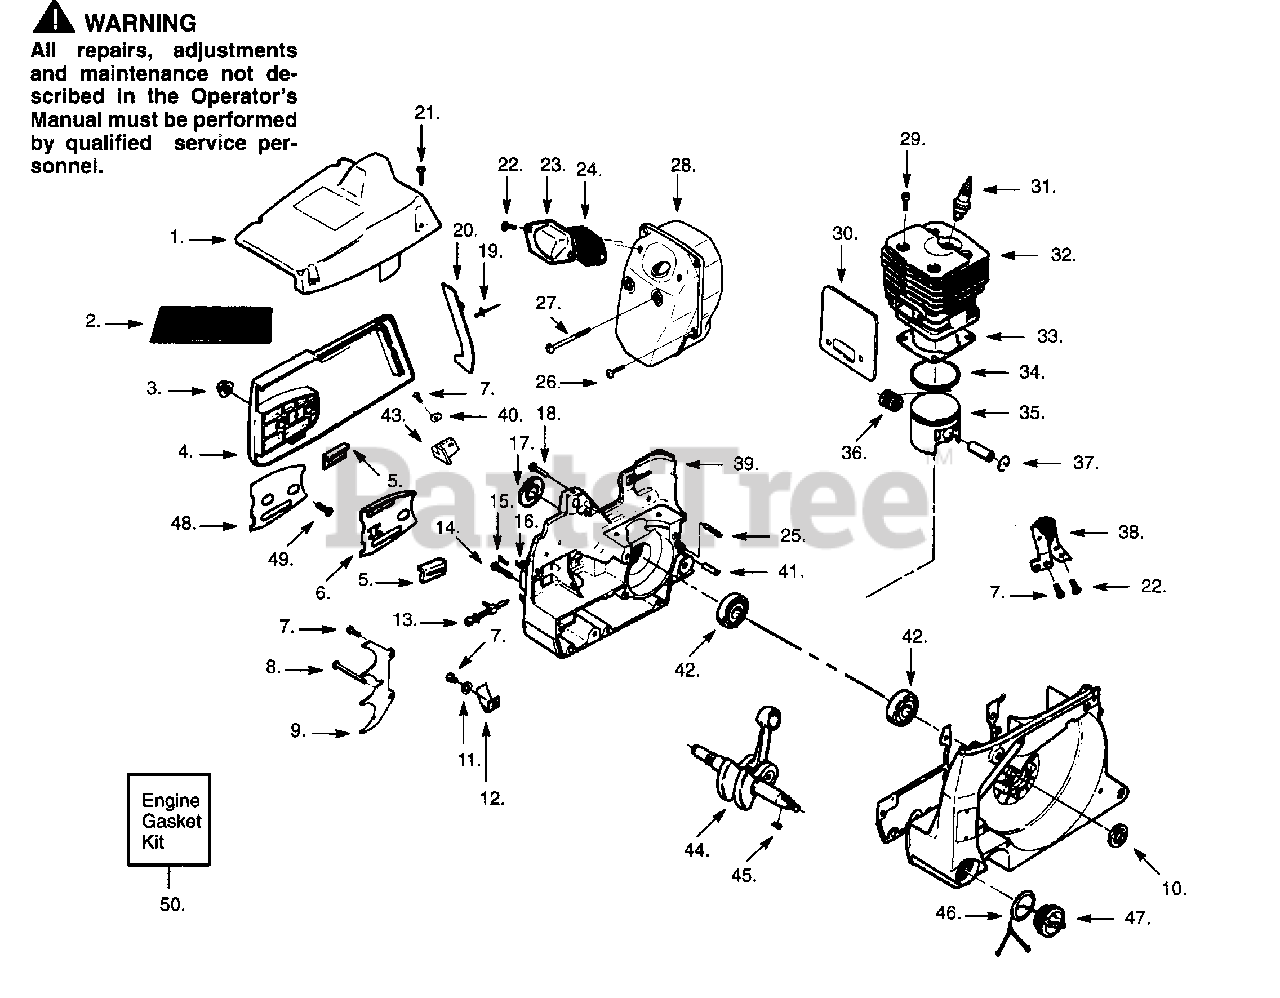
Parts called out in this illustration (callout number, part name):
1	Cylinder Cover
2	Model 415
2	Model 475 Decal (not a serviceable part)
4	Bar Clamp
5	Chain Pad
6	Bar Plate-Inner
9	Spur
10	Oil Seal
12	Chain Catcher
13	Chain Adjuster
15	Vent Pin
16	Bar Stud
17	Oil Seal
19	Pop Rivet
20	Deflector
22	Screw
23	Exhaust Deflector
24	Spark Arrestor
28	Muffler Ass'y
30	Heat Shield
31	Spark Plug
32	Model 415
32	Model 475
34	Model 415
34	Model 475
35	Model 415
35	Model 475
36	Piston Pin Bearing
38	Shock Mount
39	Crankcase Ass'y.
42	Crankshaft Bearing
43	Rear Chain Catcher
44	Crankshaft Ass'y.
45	Flywheel Key
47	Oil Cap Ass'y.
48	Bar Plate-Outer
50	Engine Gasket Kit
